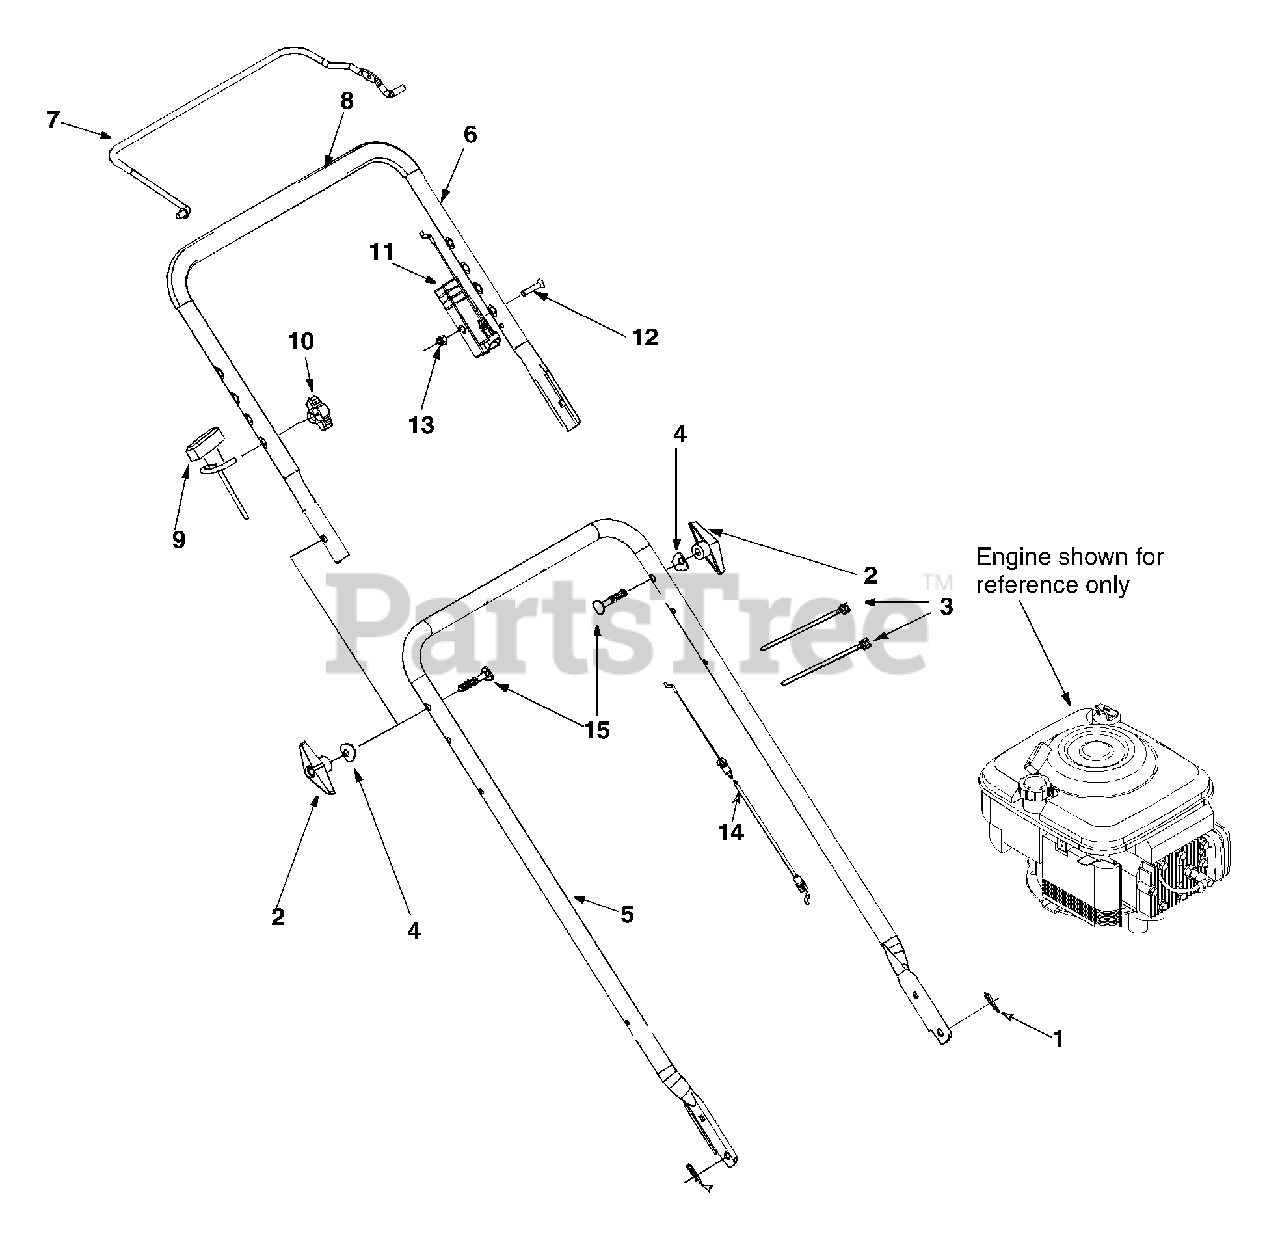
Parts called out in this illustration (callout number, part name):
1	Hairpin Clip
2	Wing Nut
3	Cable Tie
4	Saddle Washer
11	Housing Control
12	Oval C-Sunk Scr.
13	Hex L-Nut 1/4-20
14	Control Cable
15	Carriage Bolt
